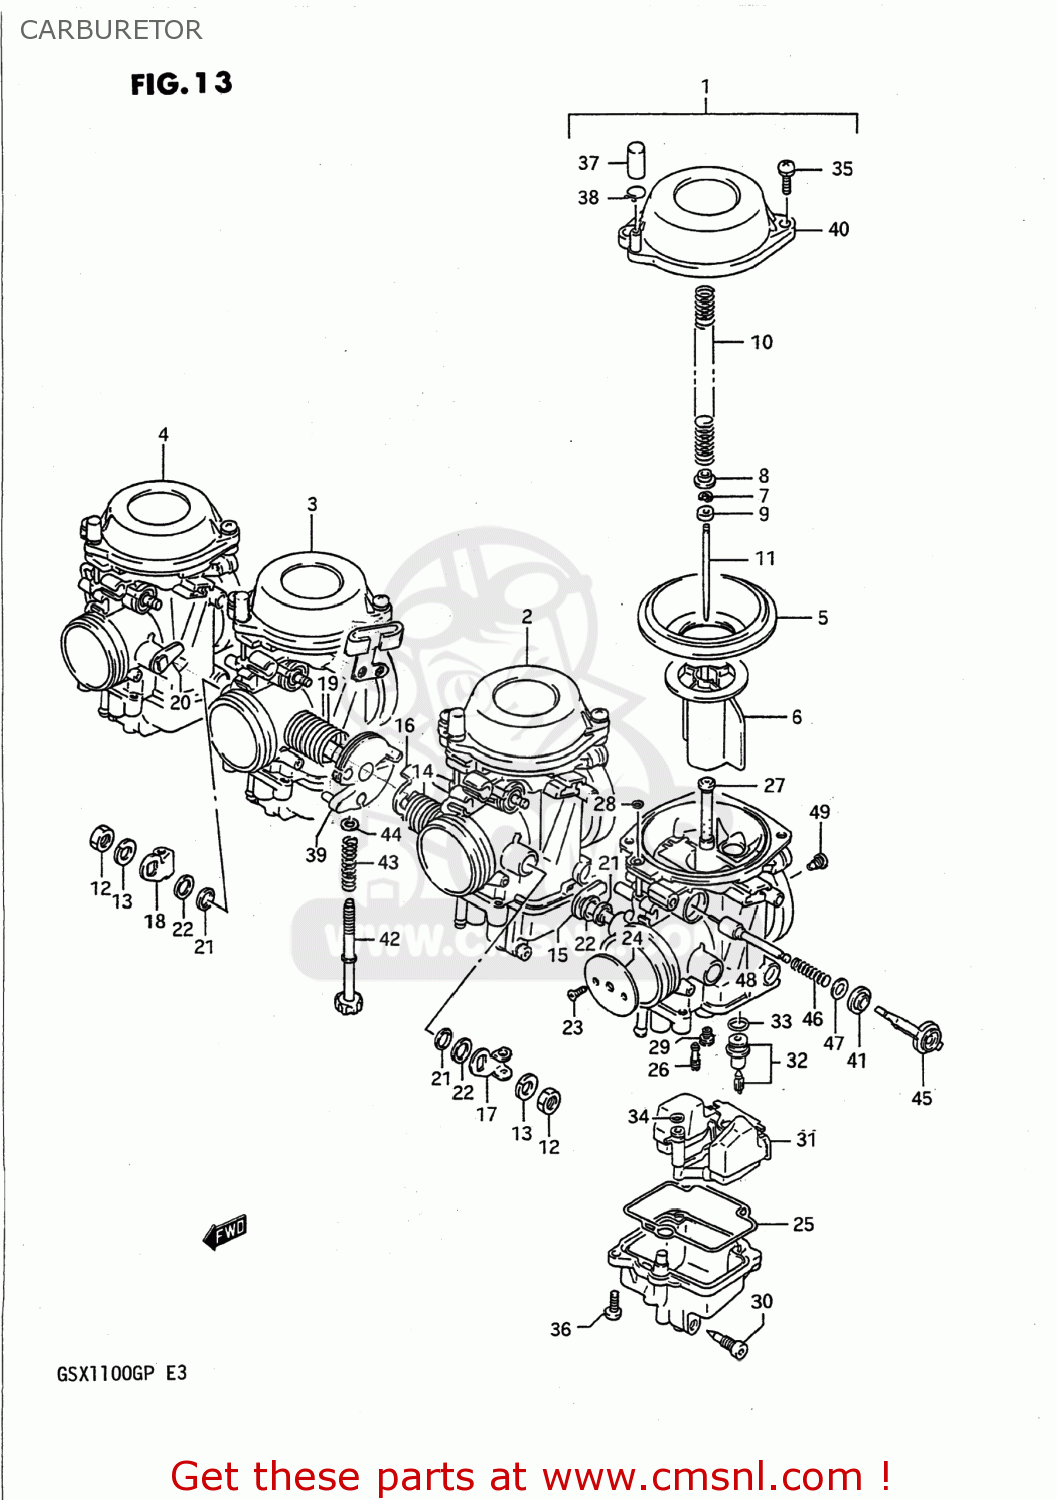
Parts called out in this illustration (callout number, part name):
1	CARBURETOR ASSEMBLY,LEFT
2	CARBURETOR ASSEMBLY,MIDDLE,LEFT
3	CARBURETOR ASSEMBLY,MIDDLE,RIGHT
4	CARBURETOR ASSEMBLY,RIGHT
5	DIAPHRAGM
6	VALVE,PISTON
7	E RING
8	RING
9	RING
10	SPRING
11	NEEDLE,JET
12	NUT
13	WASHER,LOCK,8.
14	SPRING
15	SHAFT ASSEMBLY
16	SHAFT ASSEMBLY
17	LEVER
18	LEVER,THROTTLE
19	SPRING
20	SHAFT ASSEMBLY
21	SEAL
22	GASKET,THROTTLE SHAFT (NAS)
23	SCREW
24	VALVE,THROTTLE(125)
25	GASKET,FLOAT CHAMBER (NAS)
26	JET,PILOT(30)
27	JET,NEEDLE(O-6)
28	O RING
29	JET,MAIN(120)
30	PLUG
31	FLOAT ASSY
32	VALVE ASSEMBLY,NEEDLE
33	O RING
34	O-RING,NEEDLE VALVE
35	SCREW
36	SCREW
37	CAP
38	CLIP
39	SHAFT ASSEMBLY
40	COVER,DIAPHRAGM
41	CAP,STARTER
42	SCREW
43	SPRING
44	WASHER
45	HOLDER,GUIDE
46	SPRING
47	WASHER
48	PLUNGER ASSY
49	JET,AIR(1.2)
